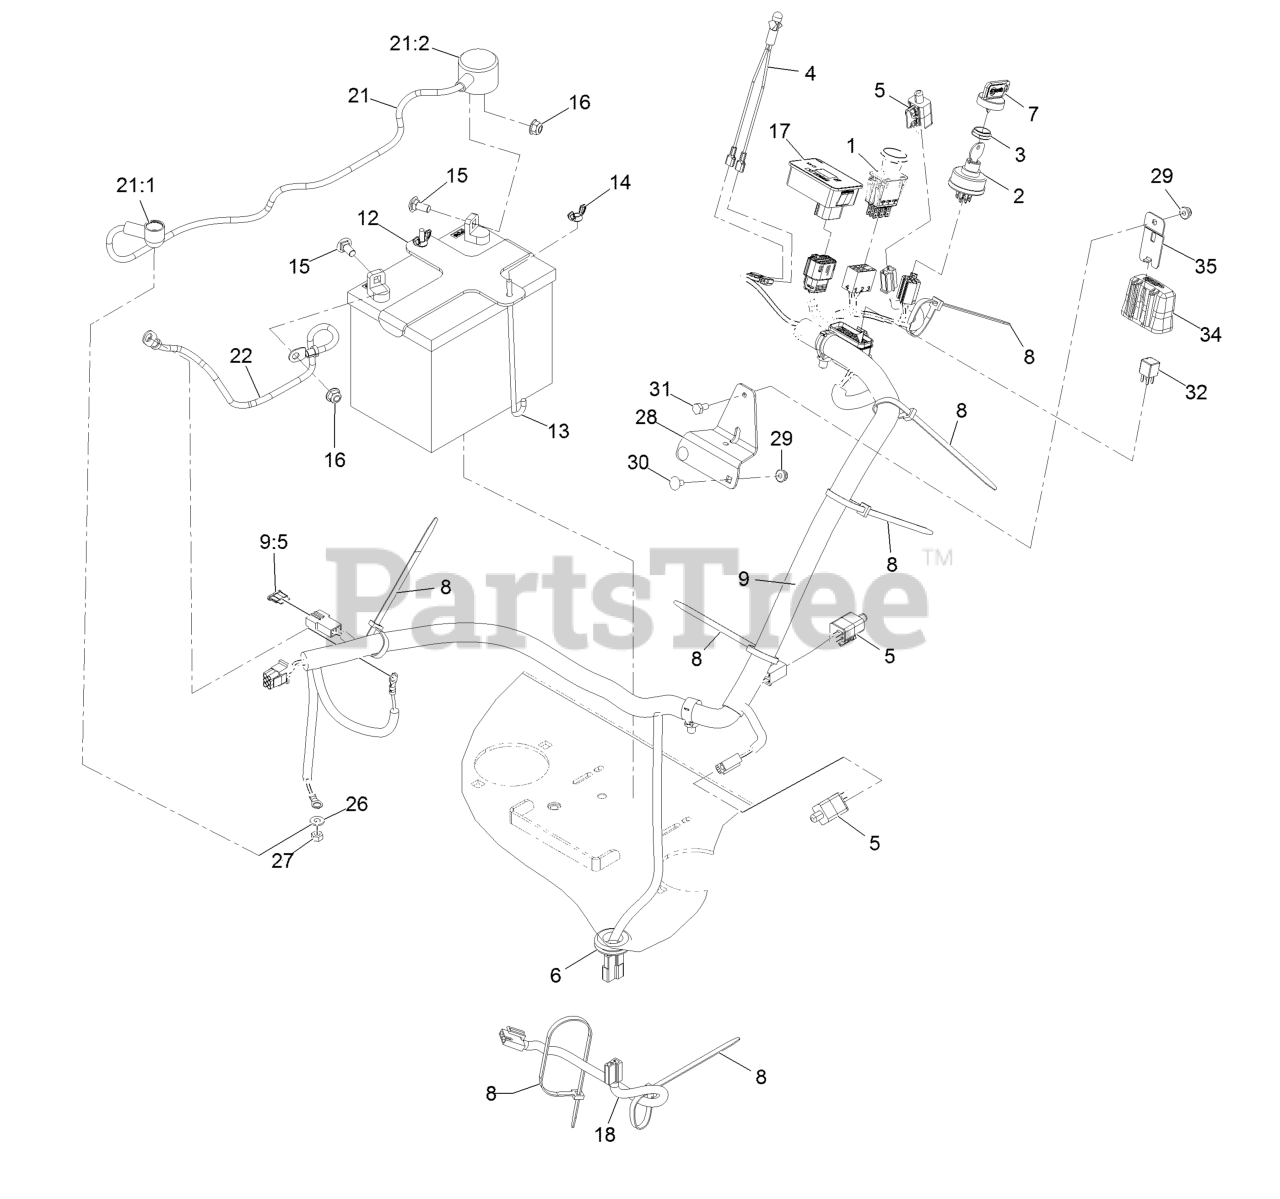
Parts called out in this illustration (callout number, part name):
1	Switch-PTO
2	Switch, Key Start
3	Nut-Ignition
4	Indicator-Red LED
6	Grommet
7	Key-Exmark Logo
8	Tie-Cable 7 15/16 (Large)
9	Harness-Wire
9:5	Fuse-Blade Type, 20 Amp
12	Bracket, Battery Hold Down
13	Bolt-Holddown
14	Wingnut-Nyloc 1/4-20
15	Bolt-Carriage 5/16-18 X 3/4
16	Nut-Nyloc 5/16-18 Flg
17	Module-Hour Meter
18	Harness-Clutch Pigtail
21	Positive Battery Cable ASM
21:1	Insulator-Solenoid
21:2	Insulator-Battery
22	Cable-Battery, Negative
26	Washer-Flat
27	Nut-Hex
28	Bracket-Mounting,Fuseblock
29	Nut-Nyloc 1/4-20 Flg
30	Bolt-Carriage 1/4-20 X 1/2
31	Screw-HH 1/4-20 X 1/2
32	Relay-Micro
34	Cover-Block, Fuse
35	Clip-Mounting
